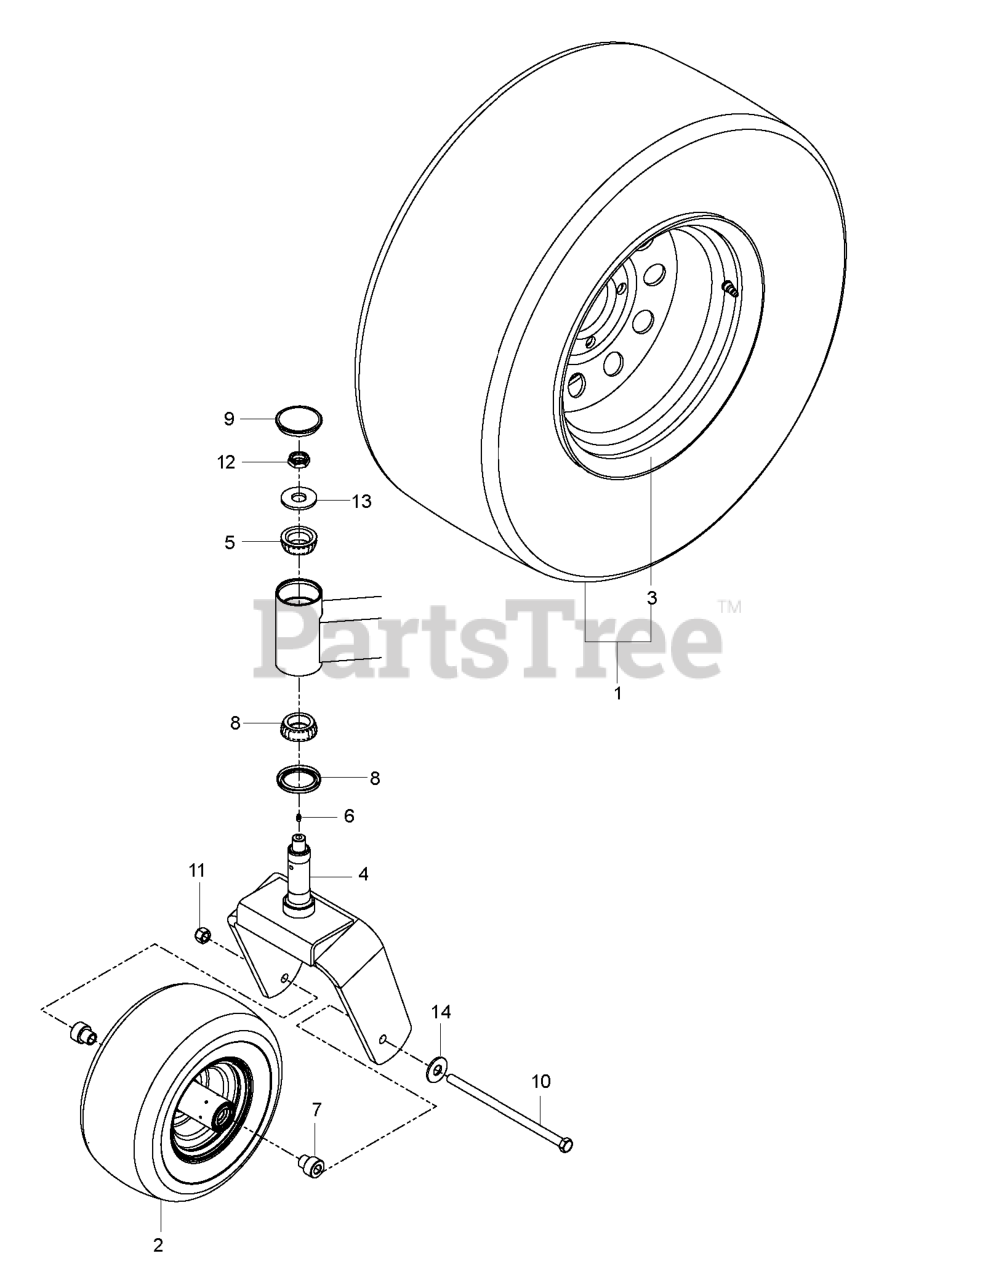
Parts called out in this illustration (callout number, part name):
1	WHEEL/TIRE.ASM SILV 23X10.5-12
2	TIRE, 13 X 6.5-6 NO FLAT
3	RIM, 12 X 8.5, 1.125" NEG OS
4	FORK.CASTER.ORANGE
5	CONE, LM67048
7	SEAL, BEARING
8	AXLE SPACER
10	HEX SCREW 1/2-13 X 9.5 GR5
11	NUT, 1/2-13 HEX FLG NYLOC ZD
12	NUT, 3/4-16 HEX THIN NYLOC ZD
13	WASHER, 3/4 HARDENED
14	WASHER 1/2" FLAT
